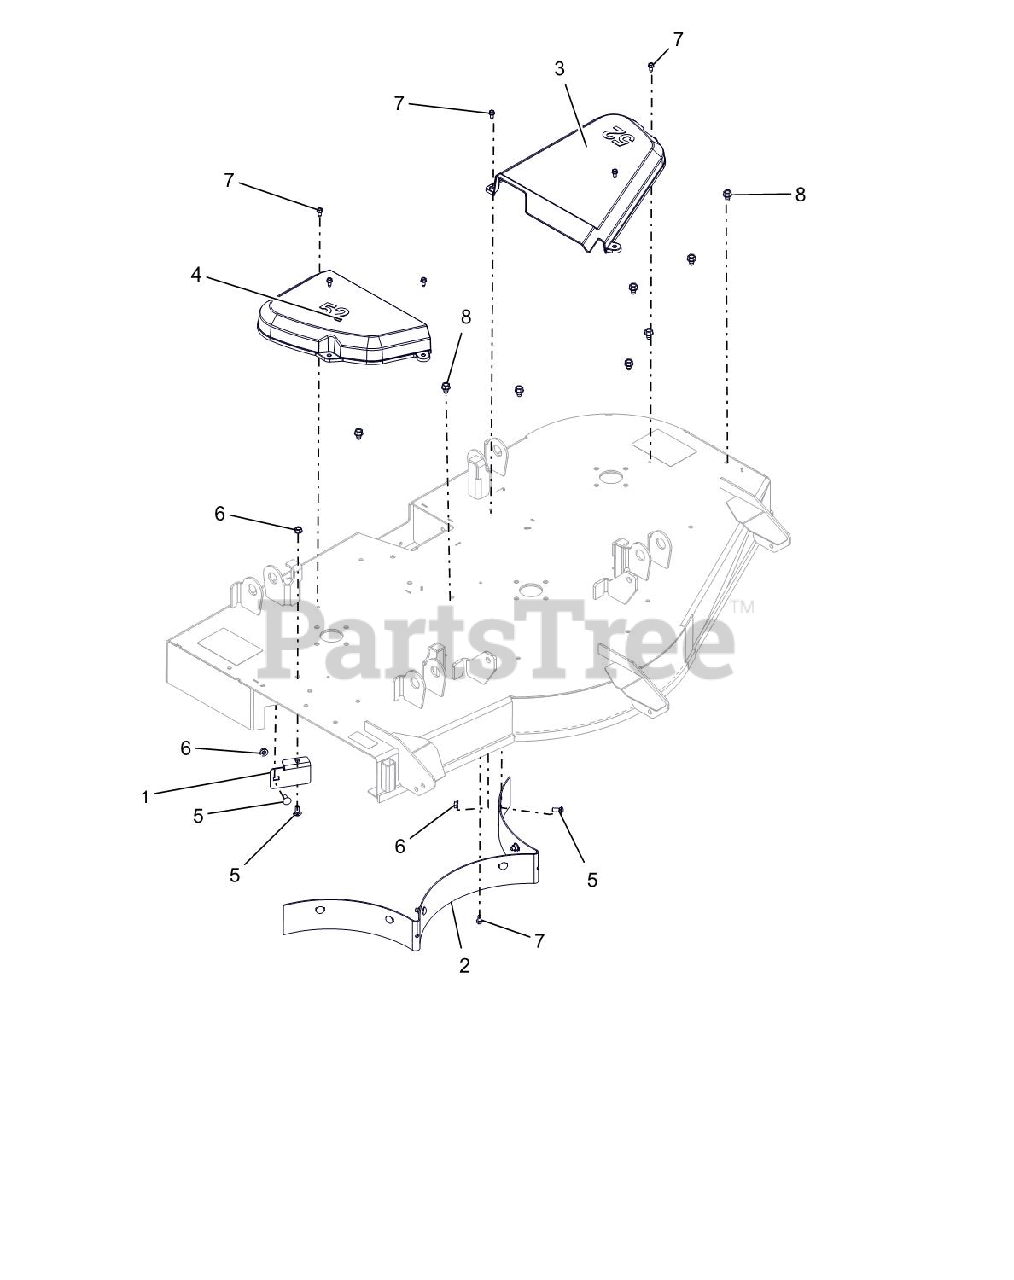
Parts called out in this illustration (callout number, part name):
1	STRIP, DEFLECTOR - 52"
2	BAFFLE, REAR - REMOVABLE 52"
3	COVER, BELT 52" LH
4	COVER, BELT 52" RIGHT
5	@BLT-RDHDSQNK .31-18X.75 G5YZ
6	@NUT-LK-TOP-FLG .31-18 YWZC
7	SCR-TAP .25-20X.50 HWH TR YWZ
8	@SCR-TAP .38-16X.50 HWH TR YWZ
